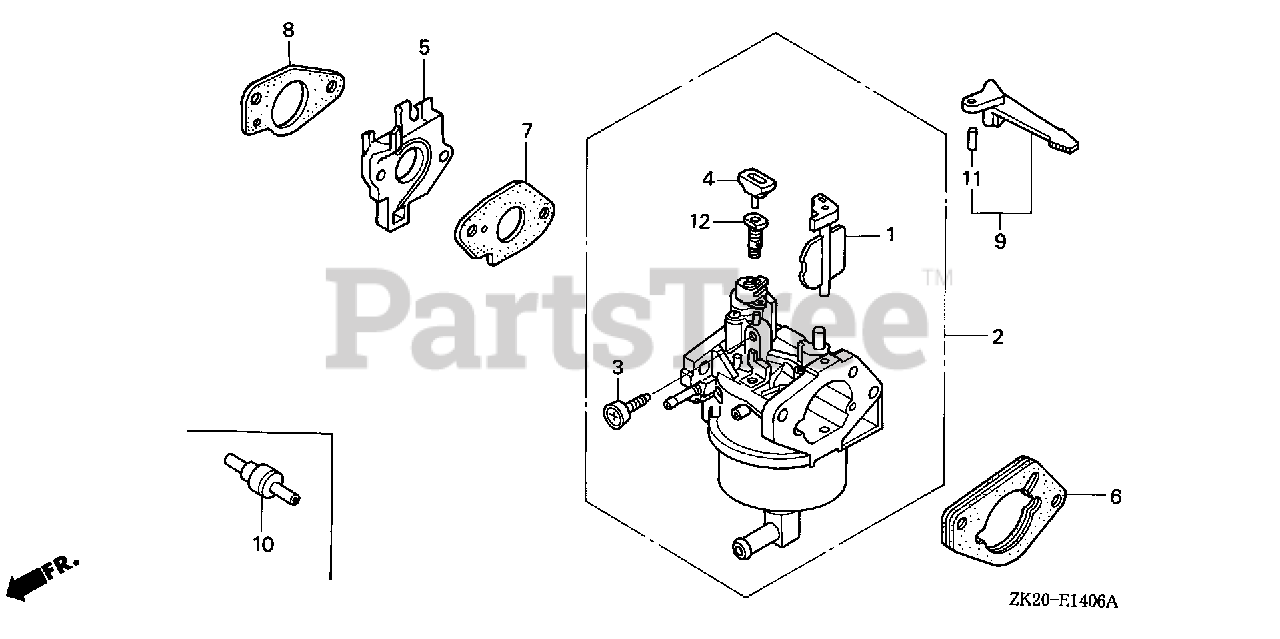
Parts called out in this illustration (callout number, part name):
2	CARBURETOR ASSY. (BEL2A A)
3	SCREW, THROTTLE STOP
4	COLLAR, SETTING
5	INSULATOR, CARBURETOR
6	SPACER, CARBURETOR
7	GASKET, CARBURETOR
8	GASKET, INSULATOR
9	LEVER, CHOKE (STD)
10	VALVE, DASHPOT CHECK
11	PIN, SPRING (2X12)
12	JET, PILOT (#45)
